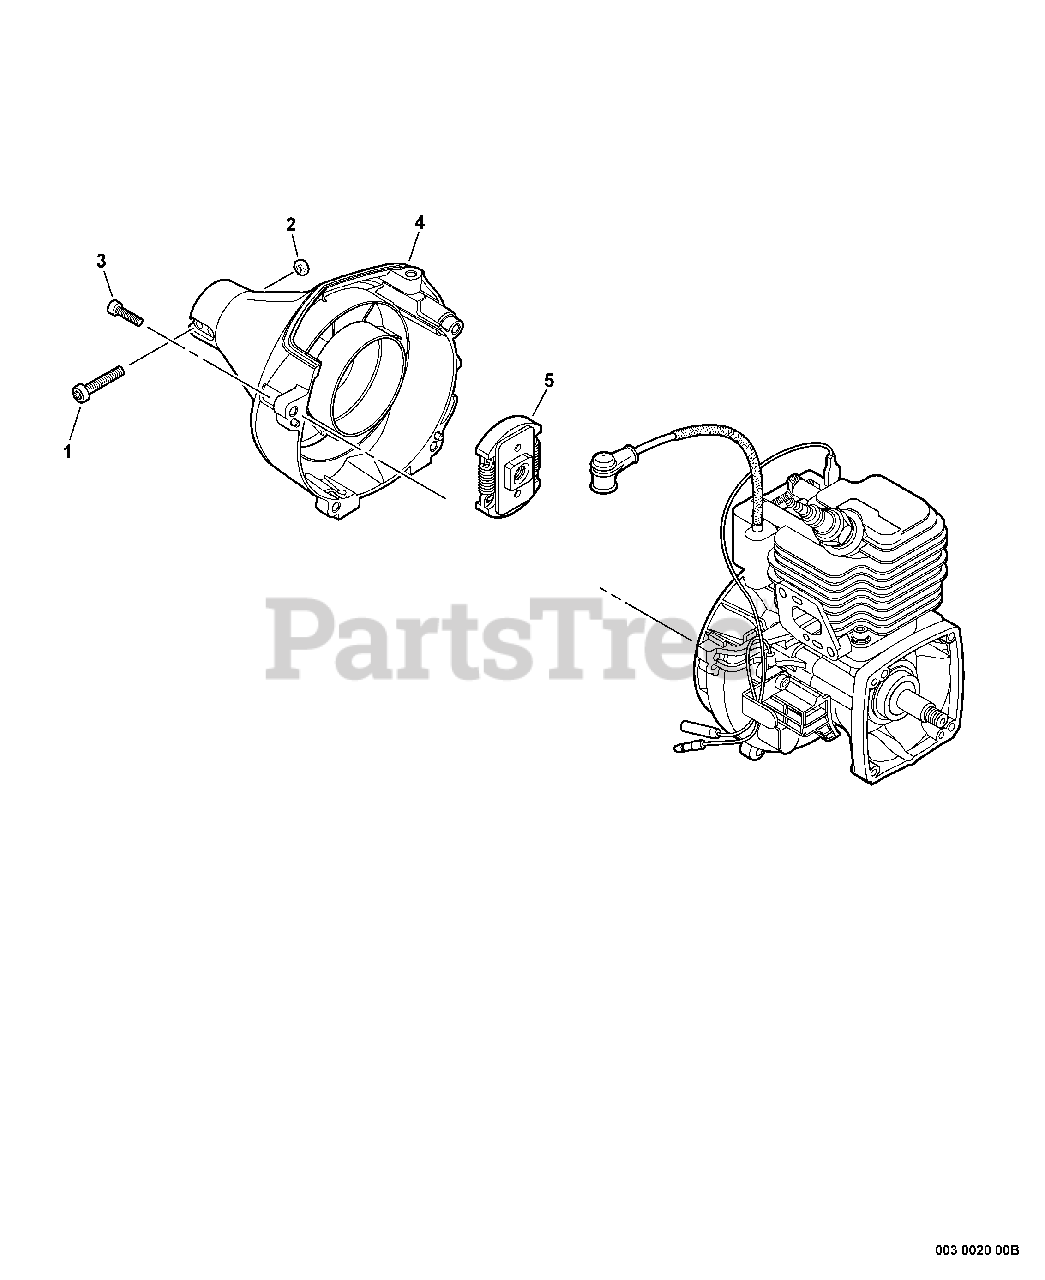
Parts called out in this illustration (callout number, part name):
1	SCREW - 5X25
3	SCREW - 4X16
4	FAN CASE ASSY
5	CLUTCH ASSY
